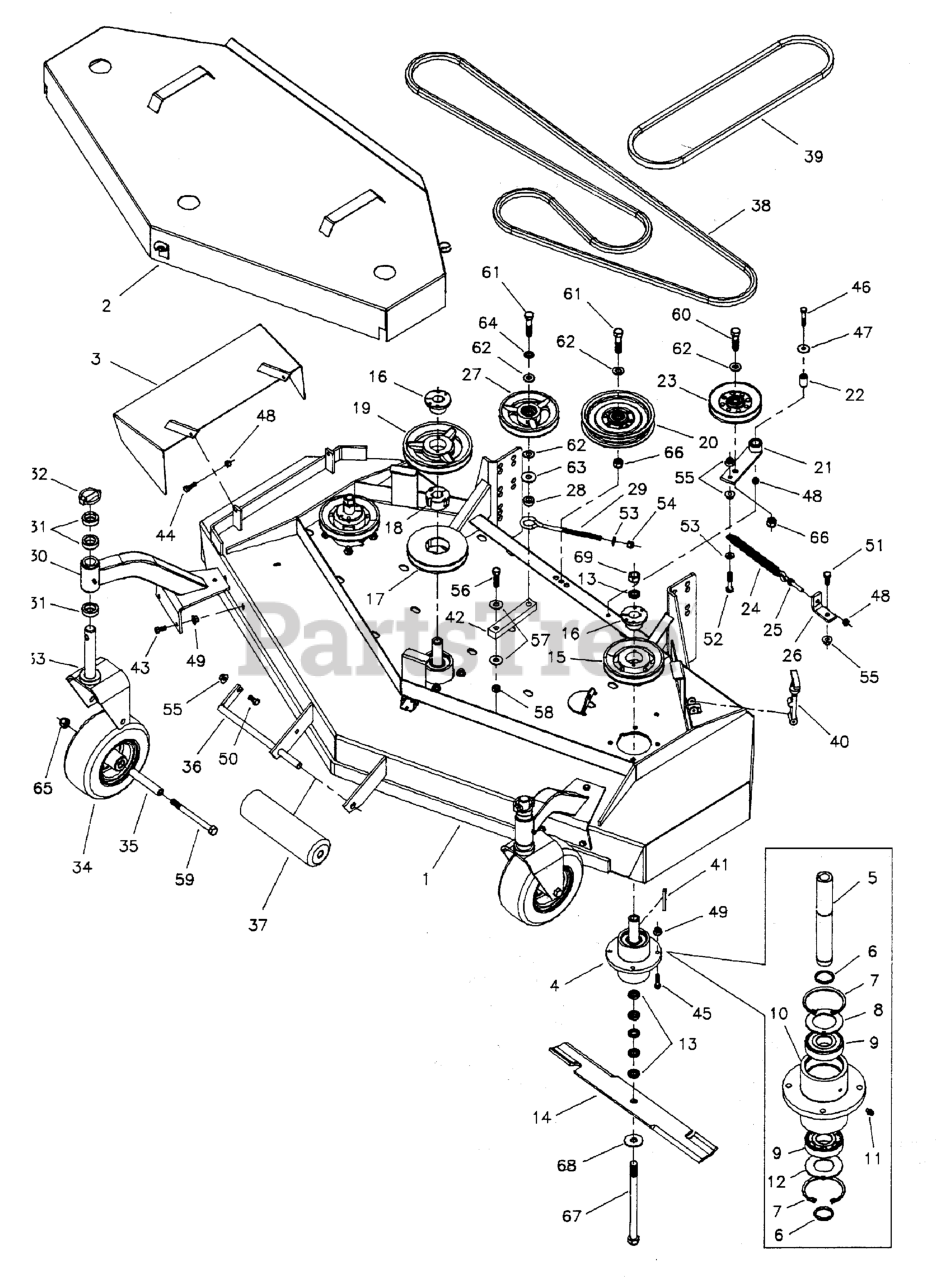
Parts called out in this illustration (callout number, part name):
1	61" MOWER HOUSING ASSEMBLY
2	61" SPINDLE COVER
3	CHUTE, DISCHARGE WELDMENT
4	SPINDLE ASSEMBLY, Complete
5	SPINDLE SHAFT
6	SNAP RING, External
7	SNAP RING, Internal
8	SPINDLE WASHER, Top
9	BEARING
10	SPINDLE HOUSING
11	GREASE FITTING
12	SPINDLE WASHER, Bottom
13	SPACER, .63 x 1.06 x .23
14	MOWER BLADE, 21"
15	PULLEY, Spindle
16	BUSHING, Tapered Hub
17	PULLEY, Taper Lock
18	BUSHING, Taper Lock
19	PULLEY, Spindle
20	PULLEY, Backside Idler
21	IDLER ARM, Complete
22	SPACER, .32 x .75 x 1.06
23	PULLEY, V-Idler
24	SPRING, Extension
25	EYEBOLT, 5/16-18 x 3-1/4
26	SPRING ANCHOR
27	IDLER PULLEY, Complete
28	SPACER, .52 X 1.00 X .38
29	EYEBOLT, 3/8" x 8"
30	CASTER MOUNT, Complete
31	SPACER, 1.02 x 1.56 x .50
32	PIN, Lynch
33	YOKE, Caster
34	WHEEL & TIRE ASSEMBLY, White, 9 x 3.5 x 4, Complete
35	AXLE, Caster Wheel
37	ROLLER
38	BELT, Blade Spindle
39	BELT, Deck Drive
40	RUBBER LATCH
41	KEY, 1/4 SQ. X 2-1/2
42	ARM, Idler
43	BOLT, 5/16-18 X 3/4 GD5
44	BOLT, 5/16-18 X 1 GD5 YZ
45	BOLT, 5/16-18 x 1-1/4
46	BOLT, 5/16-18 x 1-3/4
47	WASHER, 5/16" Fender
48	NUT, 5/16-18 Hex Nylon Lock
49	NUT, 5/16-18 HEX SERRATED FLANGE (LARGE)
50	BOLT, 3/8-16 X 3/4" GD5 CZ
51	BOLT, 3/8-16 X 1" GD5 CZ
52	BOLT, 3/8-16 X 2, GD5, CZ
53	WASHER, 3/8 SAE
54	NUT, 3/8-16 HEX NYLON LOCK
55	NUT, 3/8-16 Hex Serrated Flange
56	BOLT, 7/16-20 X 1-3/4" GD.5
57	WASHER, 7/16" SAE
58	NUT, 7/16-20 Hex Nylon Lock
59	BOLT, 1/2-13 x 5-1/2
60	BOLT, 1/2-20 x 2
61	BOLT, 1/2-20 X 2-1/4 GD5 CZ
62	WASHER, 1/2 SAE
63	WASHER, 1/2" USS
64	WASHER, 1/2" Lock
65	NUT, 1/2-13 HEX NYLON LOCK
66	NUT, Hex, Nylon Lock, 1/2-20
67	BOLT, 5/8-11 x 9-1/2
68	WASHER, 5/8" USS
69	NUT, 5/8-11 Hex
